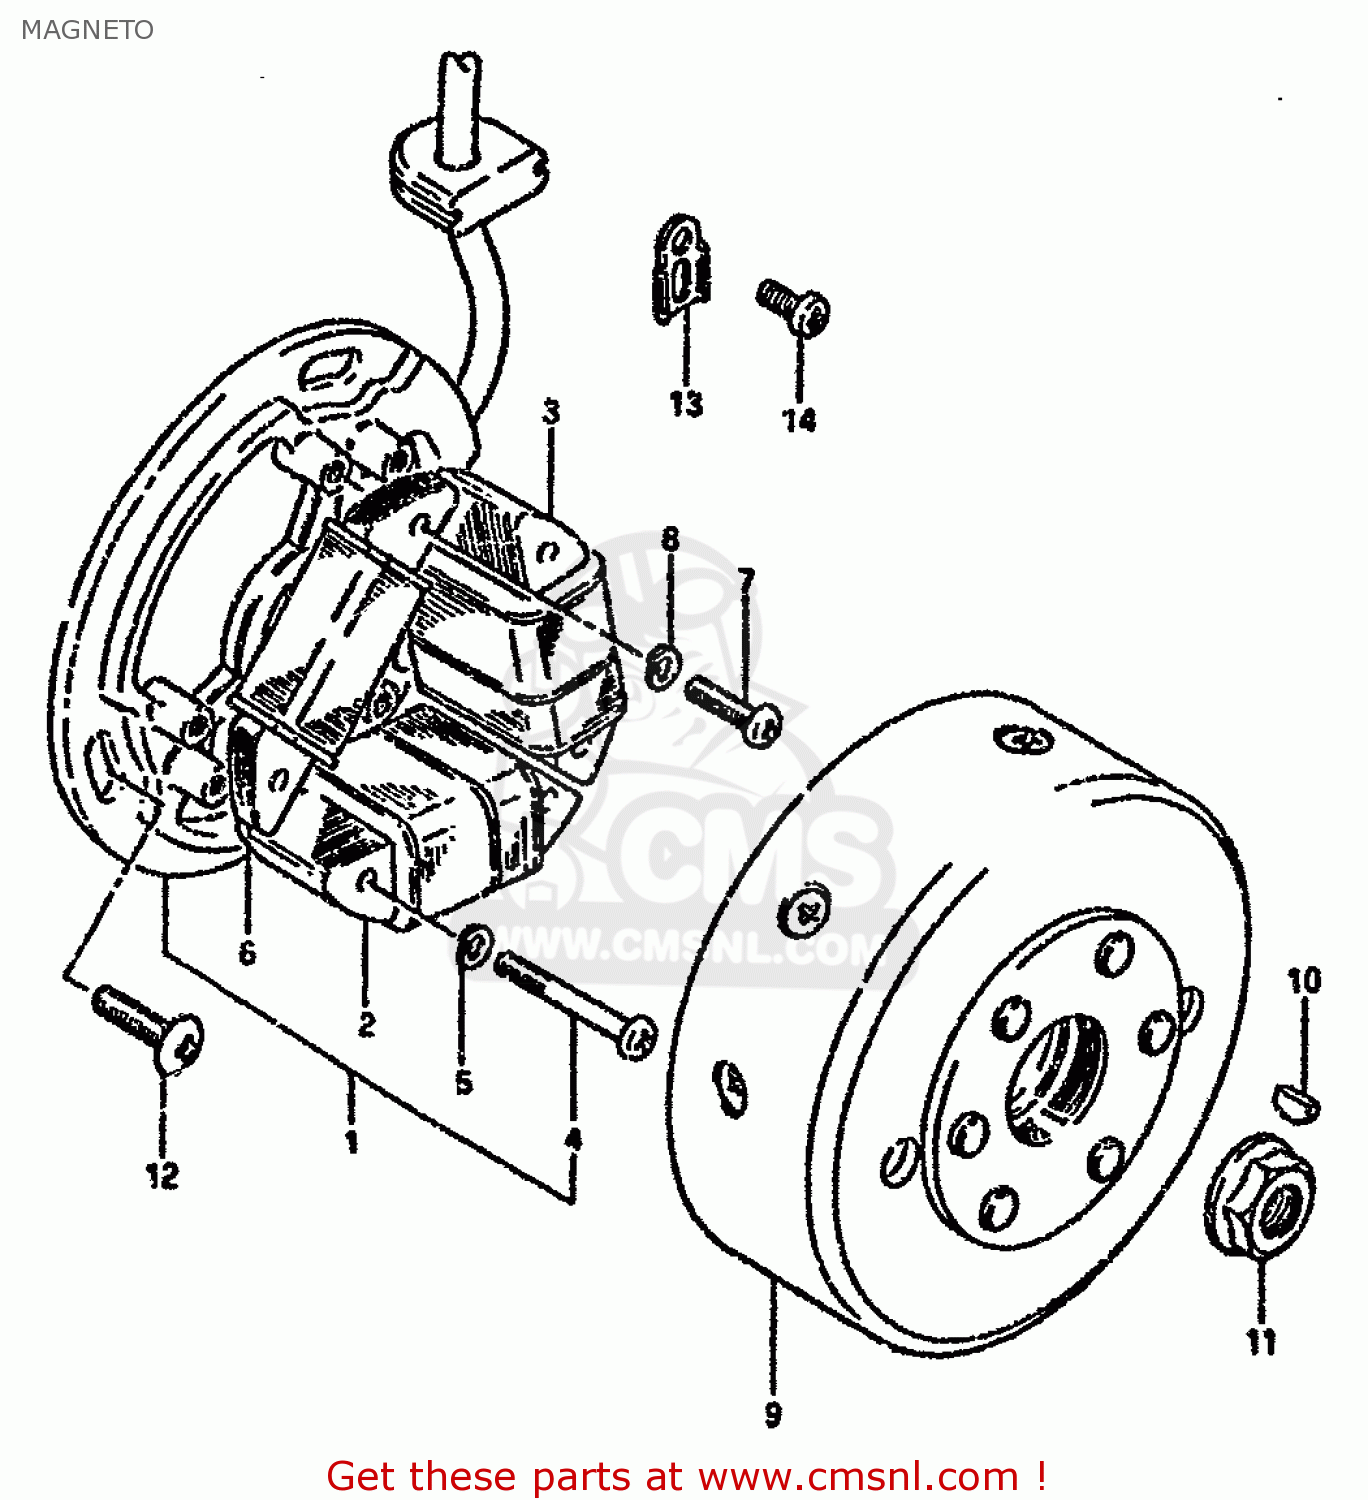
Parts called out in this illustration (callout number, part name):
1	STATOR ASSY
2	COIL,LIGHTING (A)
3	COIL,LIGHTING(B)
4	SCREW
5	WASHER,LOCK
6	COIL PRIMARY
7	SCREW
8	WASHER,LOCK
9	ROTOR
10	KEY
11	NUT
12	SCREW
13	CLAMP,GENERATOR LEAD WIRE
14	SCREW
